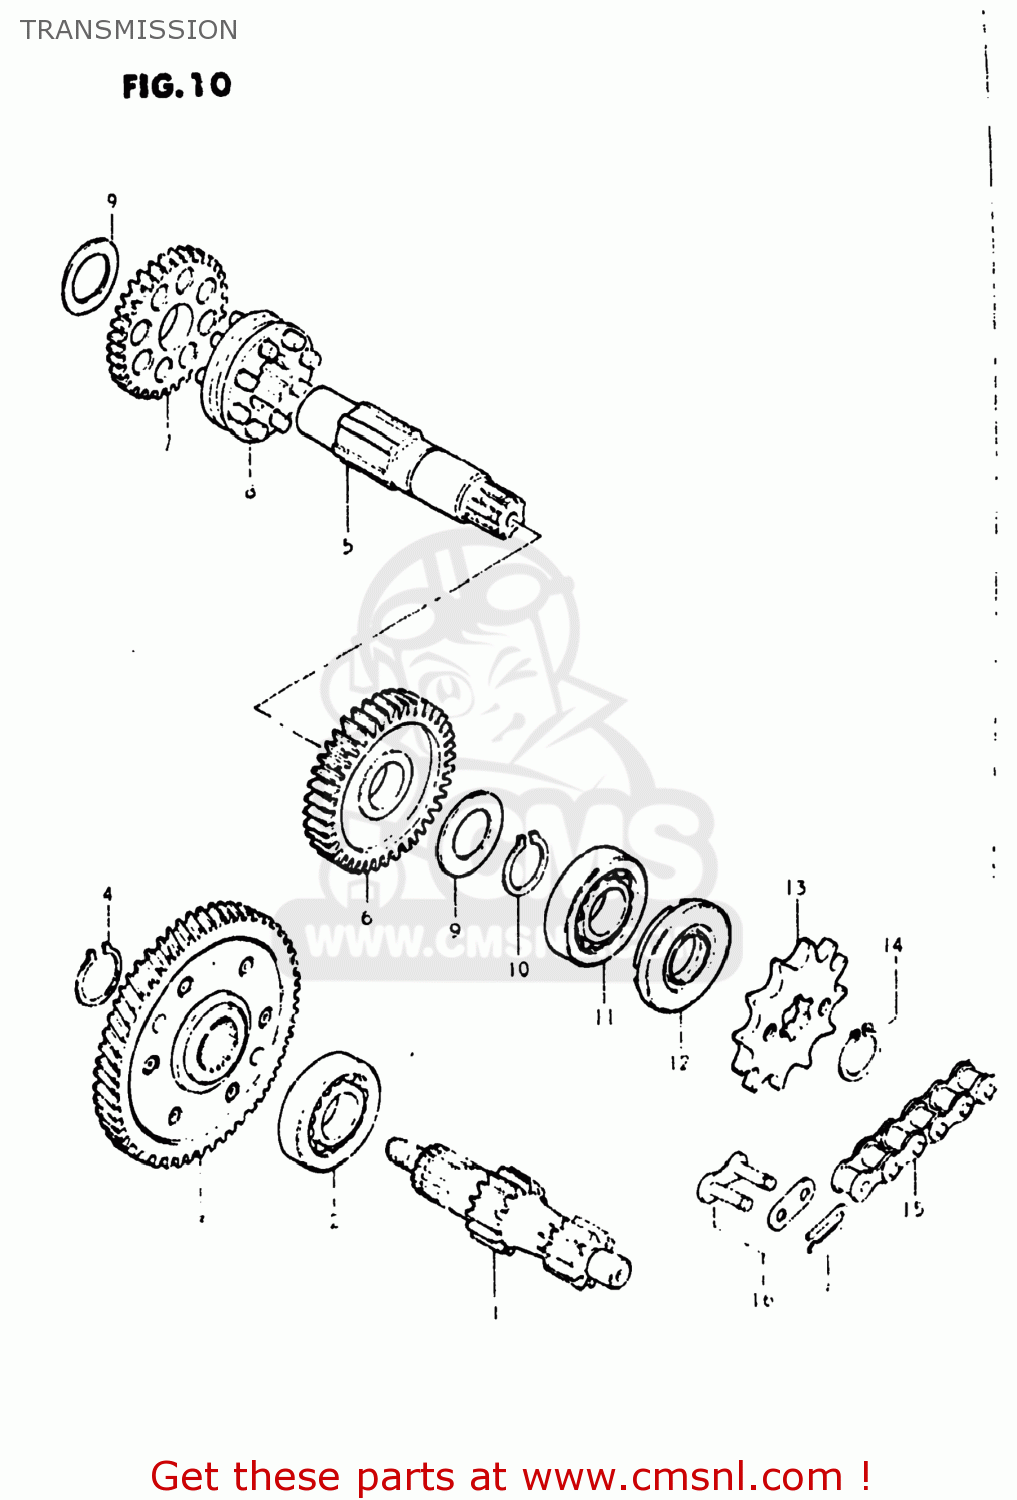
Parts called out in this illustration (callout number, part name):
1	SHAFT,COUNTER
2	BEARING
3	GEAR ASSEMBLY,PRIMARY DRIVE
4	CIRCLIP
5	SHAFT,DRIVE
6	GEAR,FIRST DRIVEN
7	GEAR,SECOND DRIVEN
8	WHEEL,FIRST GEAR
9	WASHER,THRUST
10	CIRCLIP
11	BEARING
12	SEAL,OIL(17X29X7)
13	SPROCKET,ENGINE
14	CIRCLIP,16MM
15	CHAIN ASSEMBLY,DRIVE
16	JOINT ASSEMBLY,CHAIN
